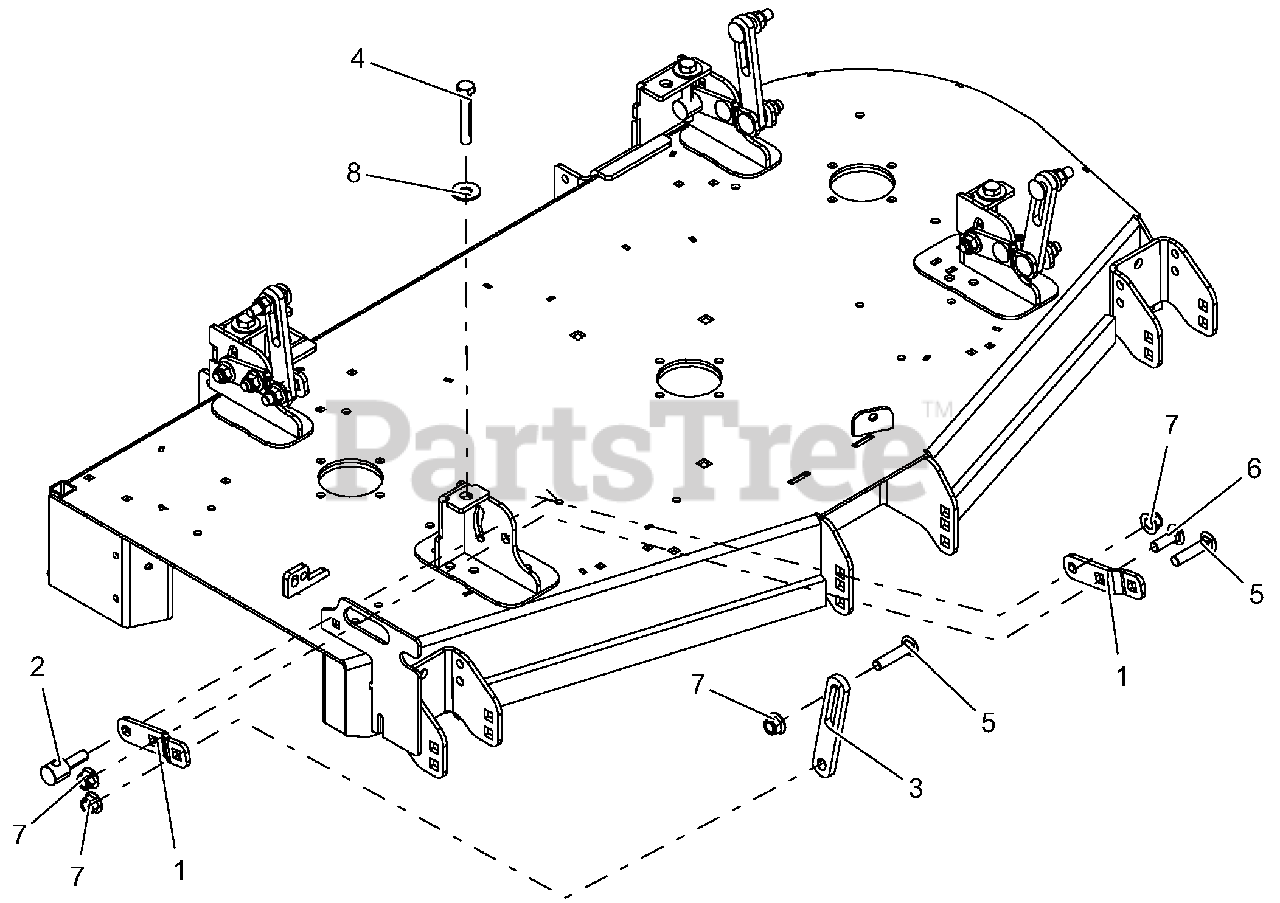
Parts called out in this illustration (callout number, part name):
1	BRKT, DECK LEVELING-BLACK
2	TRUNNION, .50-13
3	LINK, DECK LIFT - LONG
4	BLT, HEX .500-13 X 3.000 GR5 FTH YZ W/NYLON PATCH
5	BLT-RDHDSQNK .50-13X2.25 G5 Y
6	BLT-RDHDSQNK .50-13X1.50 G5 YWZC
7	NUT-LK-NYL-FLG .50-13 YWZC
8	WSHR-FL-STL.563X1.38X.109YWZC
